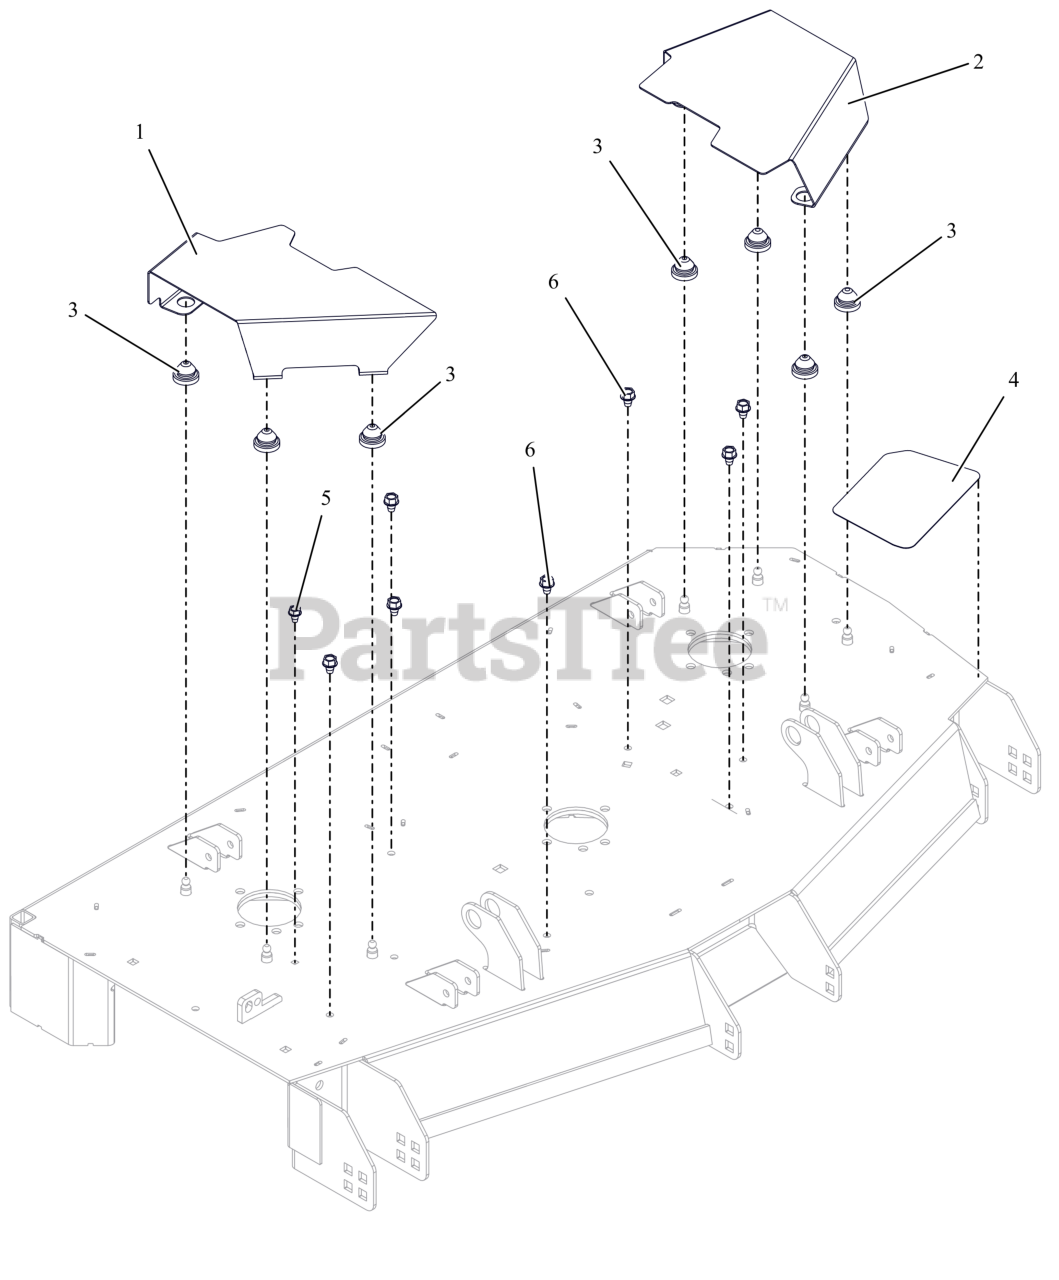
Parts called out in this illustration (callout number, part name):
1	COVER- BELT 48" RIGHT
2	COVER- BELT 48" LEFT
3	COUPLING, RUBBER PUSH-IN
4	GRIP, STEP ANTI SKID HD XF3
5	SCR,TAP .312-18X.50 HWH TR ZCC
6	SCR,TAP .375-16X.50 HWH TR ZCC
